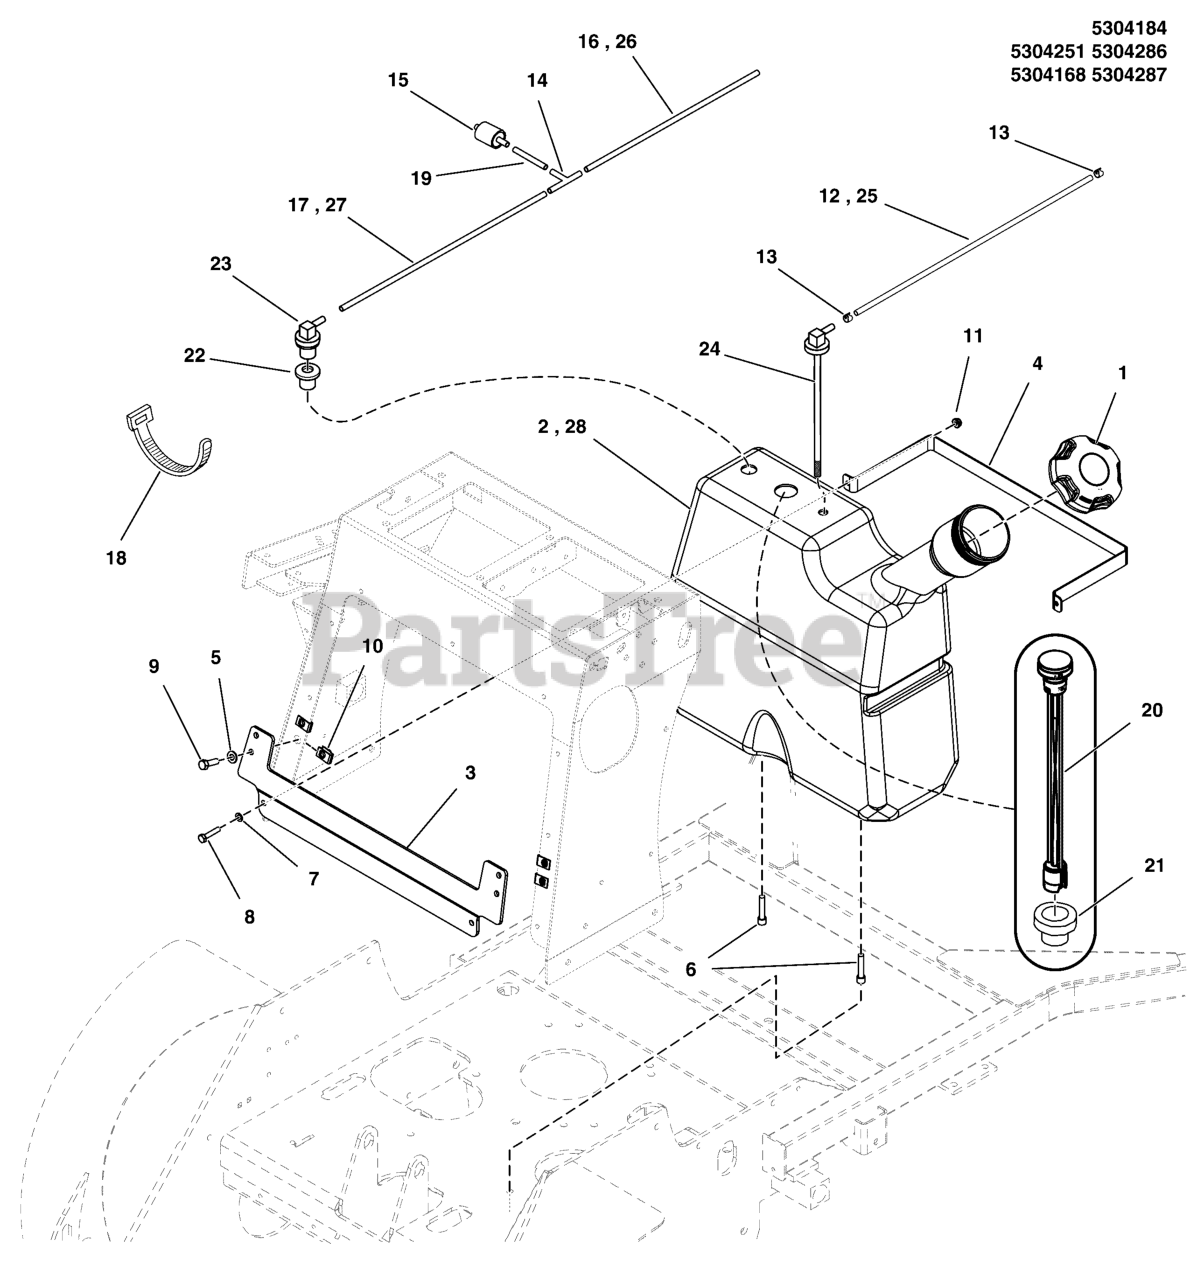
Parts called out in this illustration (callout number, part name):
1	FUEL CAP, 3.25", MANAGED VENT, 16"TETHER
2	TANK, FUEL, STAND -ON, 7.75 GALLON
3	PLATE, SRS Z2 TANK MOUNT, 7.75GAL - BLK
4	STRAP, FUEL TANK, STAND ON - BLK
5	WASHER, 5/16" SAE
6	SCREW, SOC HD, 5/16-18 X 1/2
7	WASHER, 1/4 SAE
8	BOLT, 1/4-20 X 1" GD5 CZ
9	BOLT, 5/16-18 X 1 GD5 CZ
10	BODY CLIP, 5/16-18-7GA MATERIAL
11	NUT, 1/4-20 HEX NYLOCK FLANGE
12	HOSE, 1/4" FUEL, 16.00"
13	CLAMP, HOSE, EXTERNAL, 1/2 - RED
14	FITTING, 3/16" TEE, BARB TYPE, HDPE
15	FILTER, FUEL
16	HOSE, VAPOR, 5MM ID, 5.00 LG
17	HOSE, VAPOR, 5MM ID, 15.00 LG
18	TIE,SELF-LOCKING, 6"
19	HOSE, VAPOR, 5MM ID, 2.00 LG
20	GAUGE, FUEL LEVEL, 17.0"
21	GROMMET, FUEL GAUGE
22	GROMMET
23	REMOTE VENT ASSEMBLY
24	PICKUP TUBE ASM, FUEL TANK, 16.50"
25	HOSE, 1/4" FUEL, 21.00"
26	HOSE, VAPOR, 5MM ID, 18.00 LG
27	HOSE, VAPOR, 5MM ID, 21.00 LG
28	KIT, LARGE CAPACITY FUEL TANK, SRS Z2
